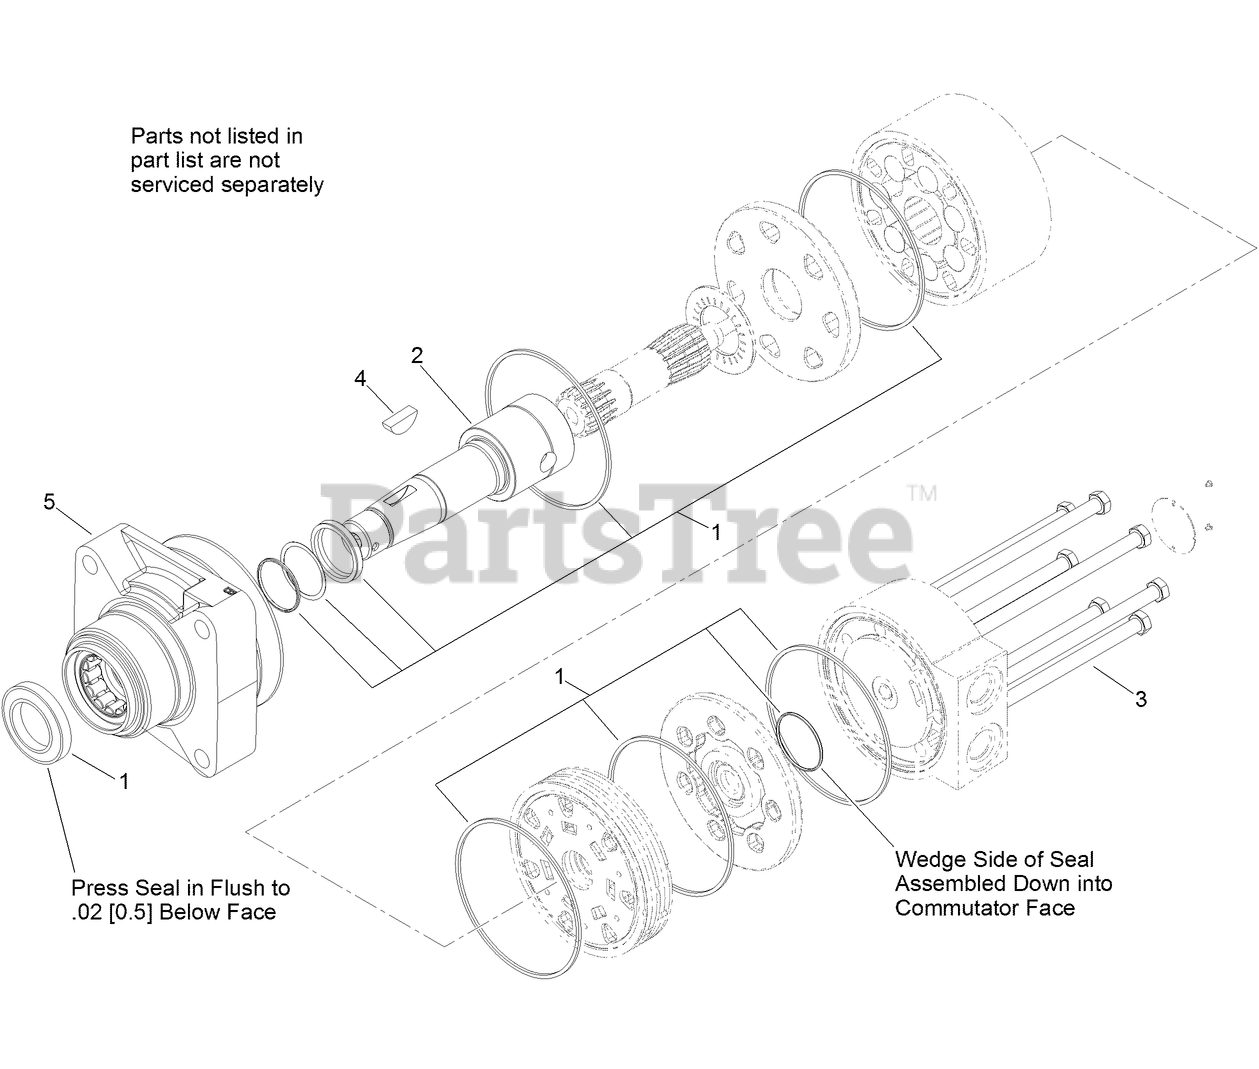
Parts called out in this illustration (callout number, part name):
1	SEAL KIT
2	COUPLING-SHAFT
3	SCREW-HH
4	KEY-WOODRUFF
5	MOTOR HOUSING ASM
